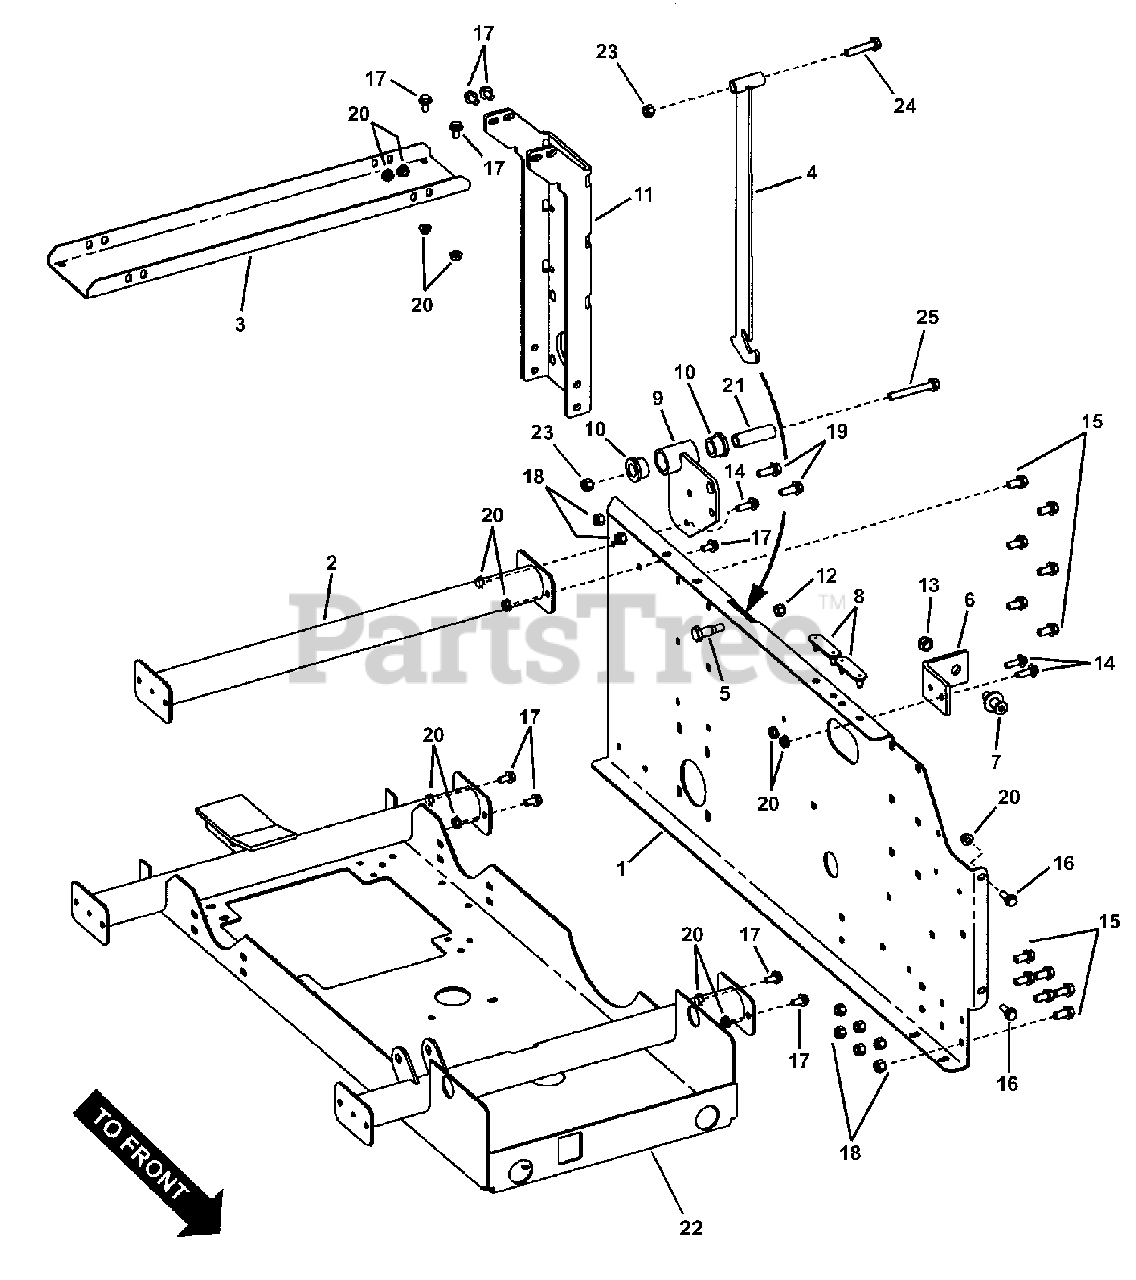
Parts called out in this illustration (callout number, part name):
1	FRAME, Rear, LH, Used on Turf Cruiser Models 85632 & 85668
1	FRAME, Rear, LH, Used on Trail Cruiser Model 85903
2	BRACE ASSEMBLY, Tube, Used on Turf Cruiser Models 85632 & 85668
2	BRACE ASSEMBLY, Tube, Used on Trail Cruiser Model 85903
3	CHANNEL, Frame Stiffener, Used on Turf Cruiser Models 85632 & 85668
3	CHANNEL, Frame Stiffener, Used on Trail Cruiser Model 85903
4	PROP ASSEMBLY, Bed
5	BOLT, Hex Head Shoulder, 3/8-24 x .760 GR 5
6	BRACKET, Bed Latch
7	PIN, Bed Latch Striker (7/16-14 thread)
8	BUMPER, Rubber
9	PIVOT ASSEMBLY, Dump Bed, Used on Turf Cruiser Models 85632 & 85668
9	PIVOT ASSEMBLY, Dump Bed, Used on Trail Cruiser Model 85903
10	BUSHING, Suspension
11	STIFFENER, CVT Frame, Used on Turf Cruiser Models 85632 & 85668
11	STIFFENER, CVT Frame, Used on Trail Cruiser Model 85903
12	NUT, Hex Nyloc, 3/8-24
13	NUT, Hex Nyloc, 7/16-14
14	BOLT, Hex Flange Lock, 5/16-18 x 1
15	SCREW, Hex Washer Self-Tap, 3/8-16 x 3/4
16	BOLT, Hex Flange Lock, 5/16-18 x 7/8
17	BOLT, Hex Flange Lock, 5/16-18 x 5/8 GR 5
18	NUT, Hex Nyloc, 3/8-16
19	BOLT, Hex Flange Lock, 3/8-16 x 1 GR 5
20	NUT, Hex Flange Lock, 5/16-18 GR 5
21	SLEEVE, Suspension
22	DRIVE BASE ASSEMBLY
23	NUT, Hex Nyloc, 1/2-13
24	CAPSCREW, Hex Head, 1/2-13 x 3
25	BOLT, Hex Head, 1/2-13 x 3-3/4 GR 5
